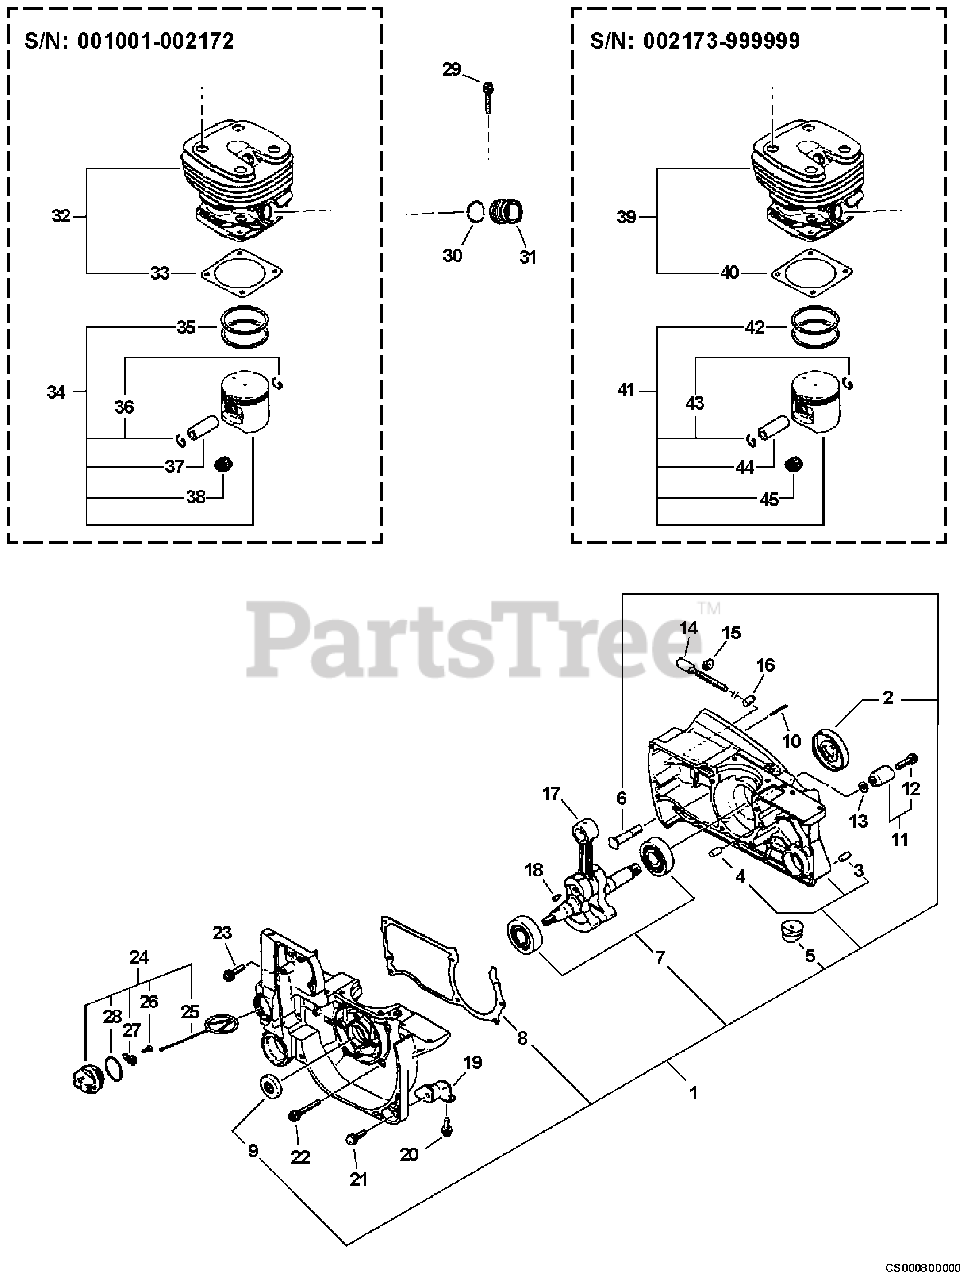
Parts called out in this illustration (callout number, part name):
1	CRANKCASE KIT - GRAY
2	SEAL, OIL
3	PIN - SPRING -- 5X10
4	PIN - LOCATING
6	STUD, GUIDE BAR
7	BEARING, BALL - 6203
8	GASKET, CRANKCASE
9	SEAL, OIL
10	VENT, TANK
11	CHAIN CATCHER KIT
12	SCREW - 5X20
13	WASHER - 5
14	SCREW, TENSIONER
16	TENSIONER, CHAIN
17	CRANKSHAFT ASSY
20	SCREW - 5X14
21	SCREW - 5X14
22	SCREW - 5X35
23	SCREW - 5X20
24	CAP ASSY
25	CONNECTOR, CAP
26	SCREW - 3X8
27	RETAINER
28	O-RING - 25
29	SCREW - 6X25
31	ADAPTOR, INTAKE
32	CYLINDER KIT
33	GASKET, CYLINDER
34	PISTON KIT
35	RING, PISTON
36	RING, RETAINING
37	PIN, PISTON
38	BEARING, NEEDLE
39	CYLINDER ASSY
40	GASKET, CYLINDER
41	PISTON KIT
42	RING, PISTON
43	RING, RETAINING
44	PIN, PISTON
45	BEARING, NEEDLE
